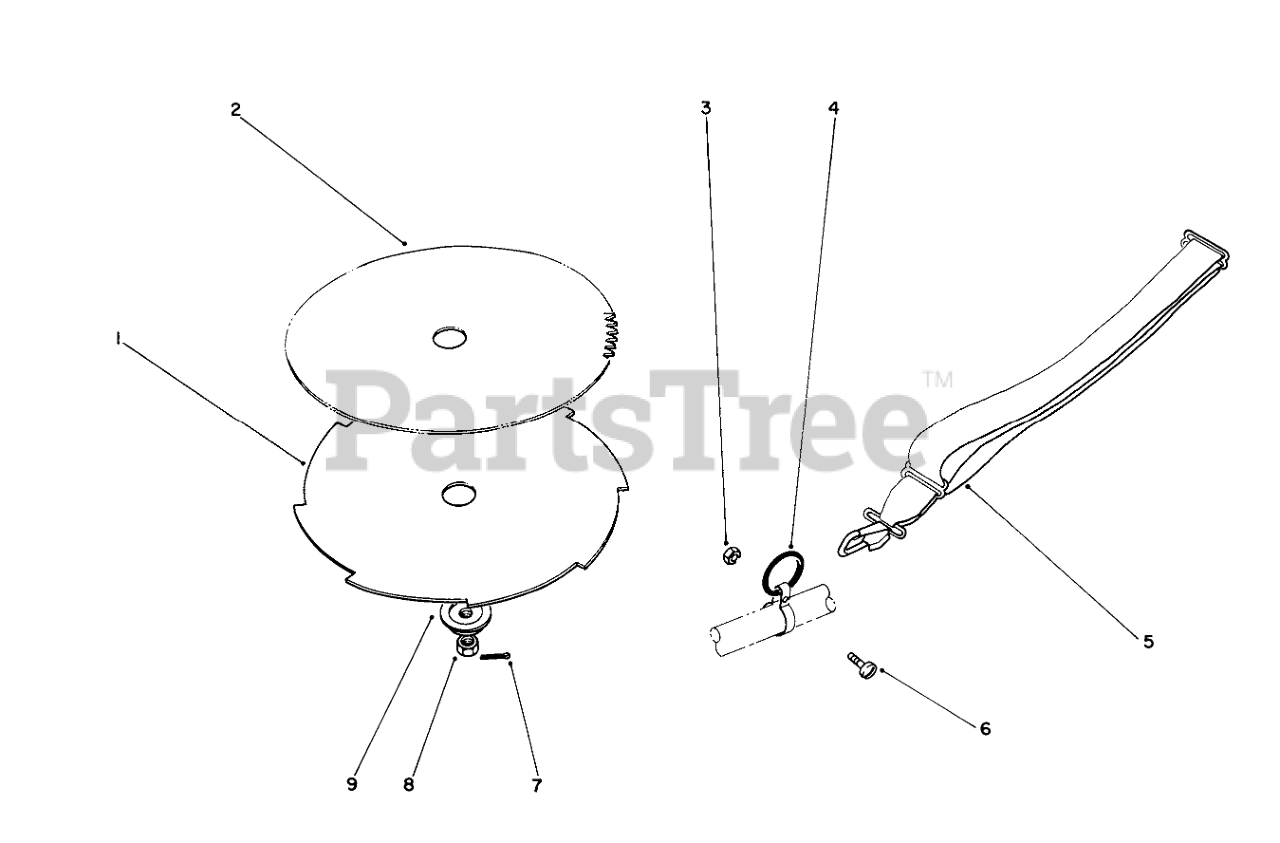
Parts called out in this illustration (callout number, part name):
1	BRUSH BLD PKG(8",8T)
2	SAW BLD PKG(8", 80T)
3	NUT-LOCK, NI
4	RING-HARNESS
5	Harness
6	SCREW-SRH
7	1/16 X 1 LG COTTER PIN
9	Adapter-Blade
